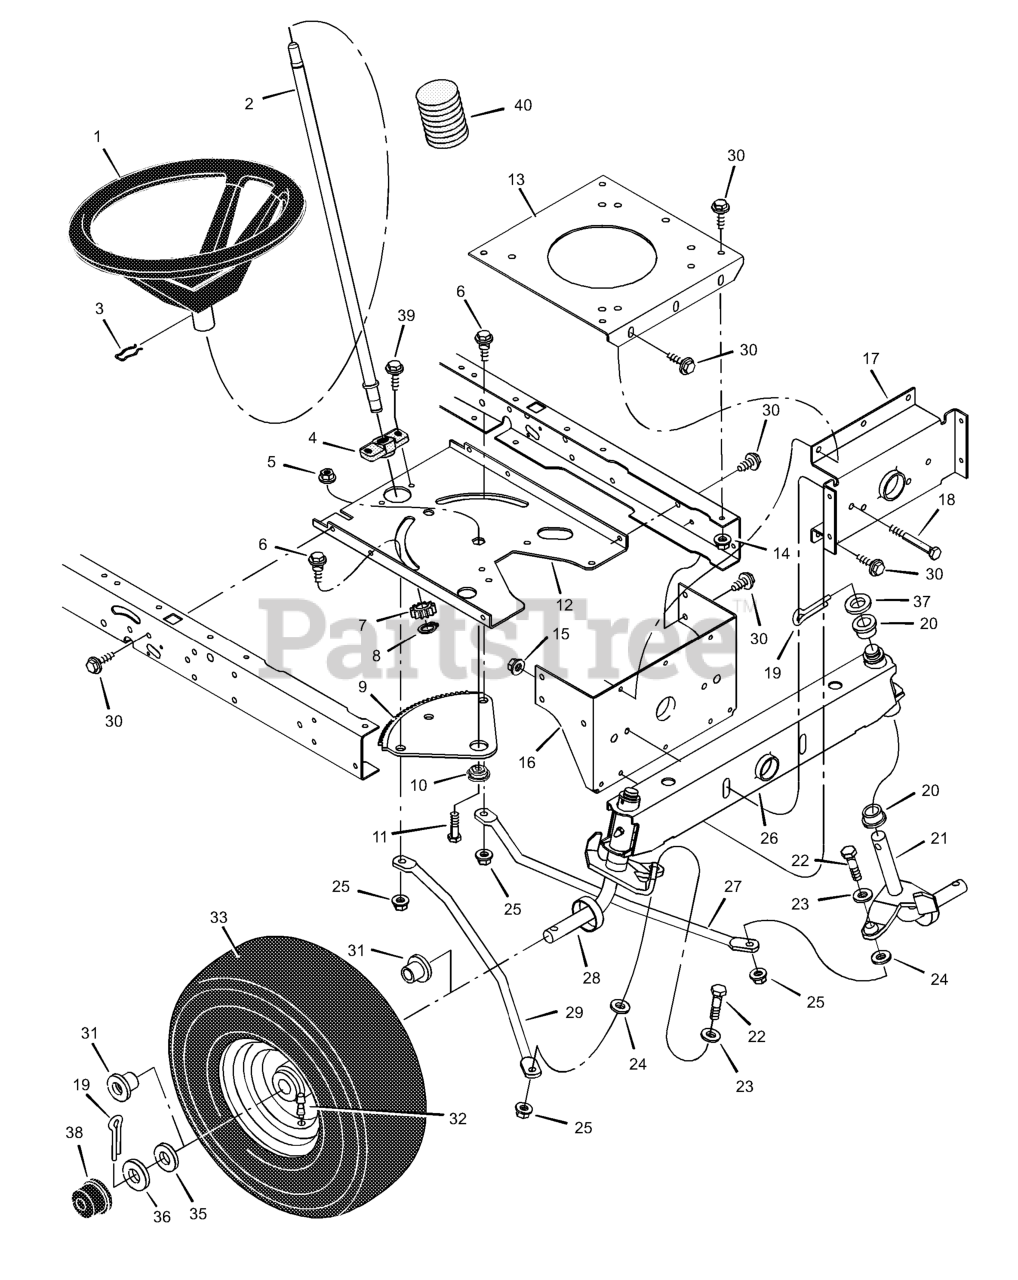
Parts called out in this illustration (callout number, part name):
1	Wheel, Steering
2	Post, Steering
3	Clip, Retainer
4	Bearing
5	Nut, Flange
6	Bolt, Shoulder
7	Gear, Pinion
8	Ring, Snap
9	Gear, Sector
10	Bearing
11	CAPSCREW, Hex Head, 5/16-18 x 1
12	Plate, Steering
13	Plate, Engine
14	Nut, Flange
15	Nut, Flange
16	Bracket, Hanger
17	Axle, Hanger
19	Pin, Cotter
20	Bearing
21	Spindle Assembly, Left
22	Bolt
23	Washer
24	Washer
25	Nut, Flange
26	Axle Assembly
27	Drag Link, Left
28	Spindle Assembly, Right
29	Drag Link, Right
31	Bearing, Wheel
32	Stem, Valve
34	Wheel and Tire Assembly
38	Hub Cap
40	Bellows
